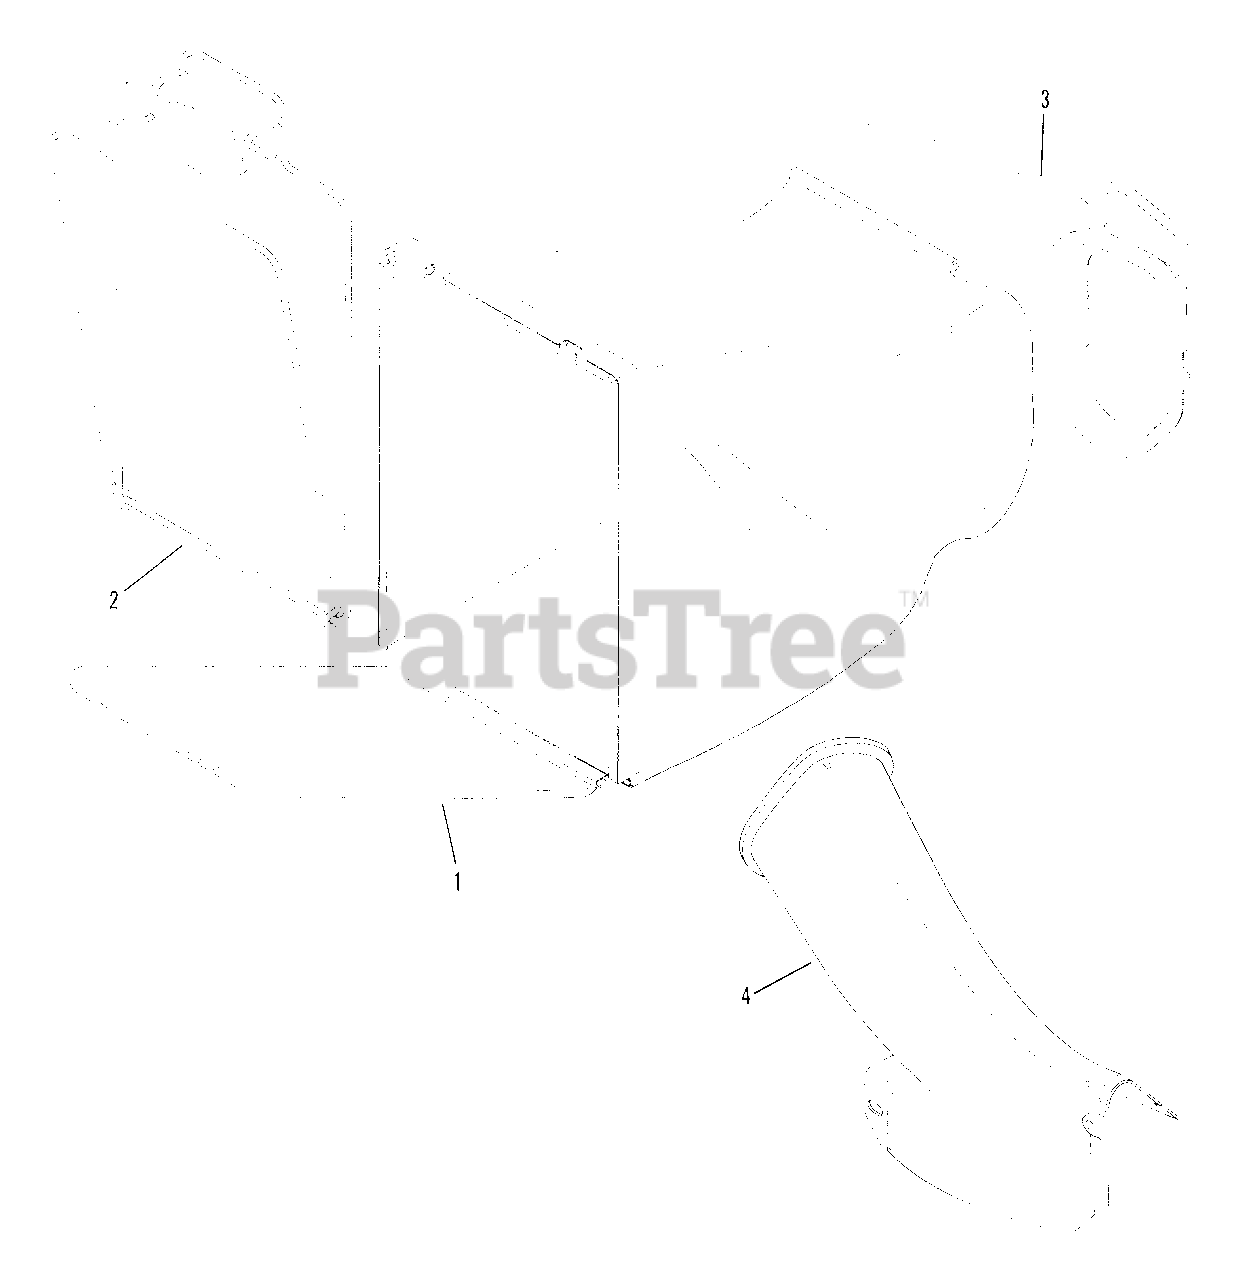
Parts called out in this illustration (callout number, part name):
1	BAG, Grass (Door Type)
2	ASSEMBLY, Bag Wire
3	CONNECTOR, Bag Wire
4	ADAPTER, Bag
